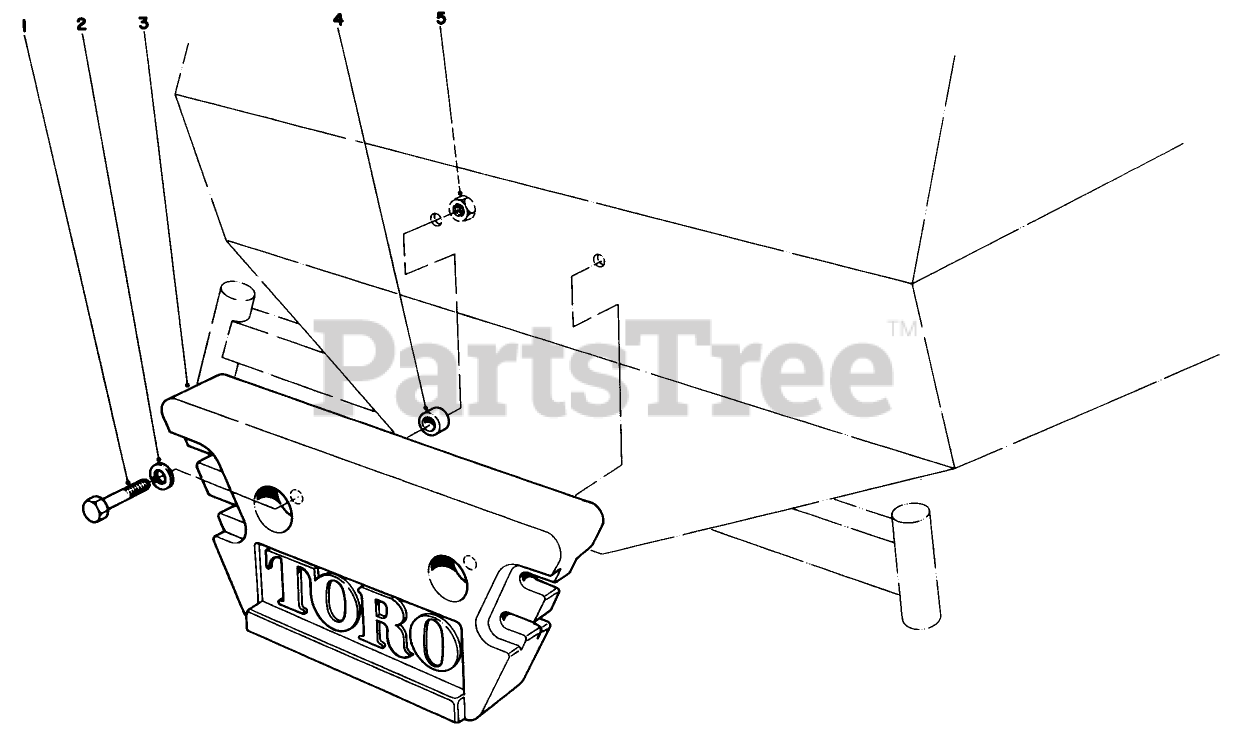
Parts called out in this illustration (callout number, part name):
1	SCREW-HH
2	SCREW-HH
4	SPACER-TUBULAR
5	NUT-HH
